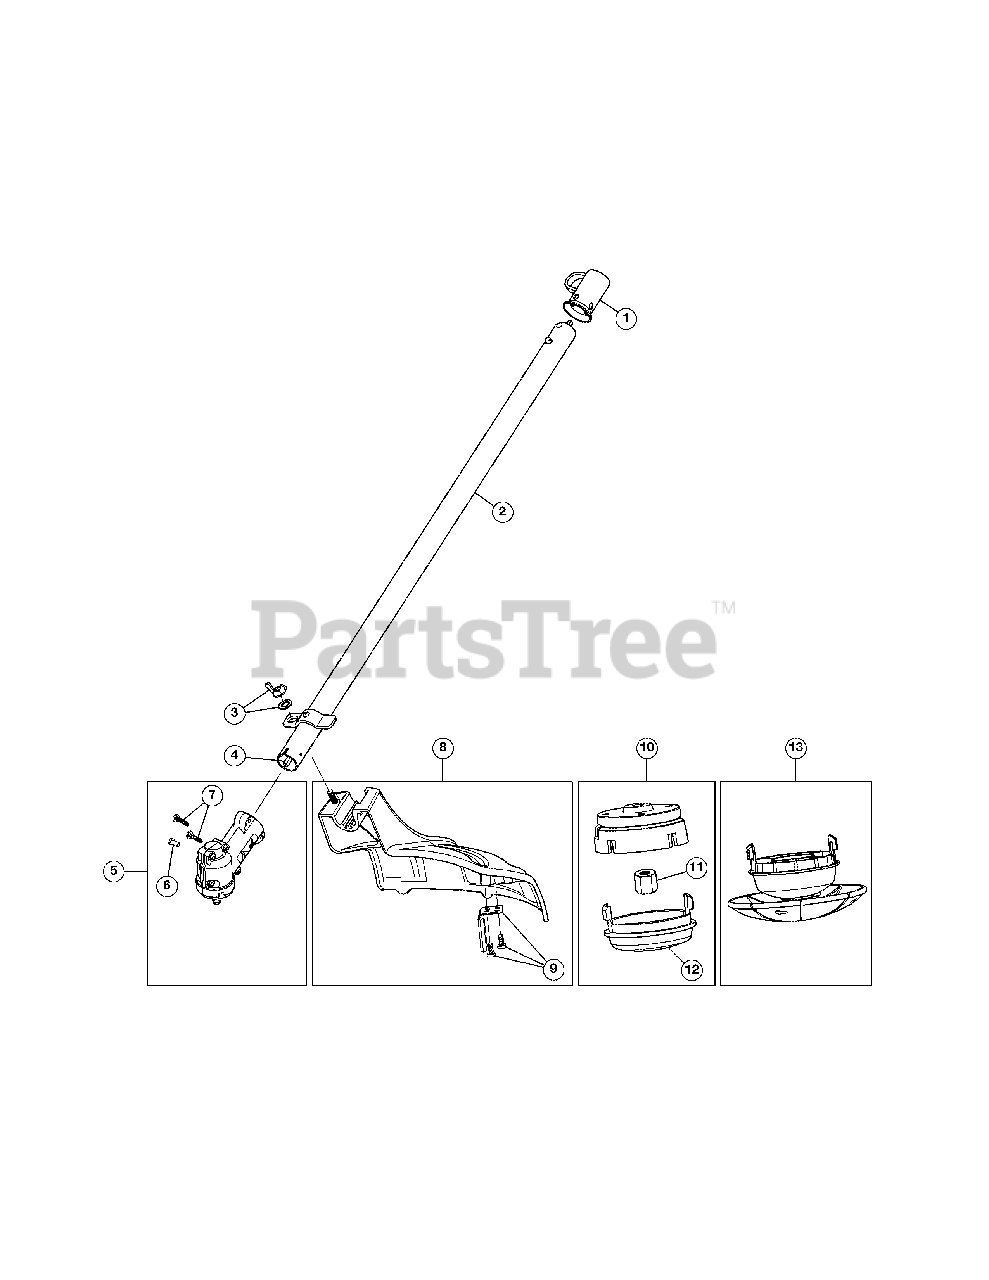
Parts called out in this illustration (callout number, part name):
1	Hanger
2	Lower Shaft Housing Assembly
3	Shield Mounting Hardware
4	Lower Flexible Drive Shaft
5	Gearbox Assembly (Incl. 6 & 7)
6	Gearbox Anti-Rotation Screw
7	Gearbox Mounting Hardware
8	Shield Assembly (Incl. 9)
9	Blade Assembly
10	Aero-Flex Cutting Head (Incl. 11 & 12)
12	Aero-Flex Cap
13	Aero-Flex Glider
